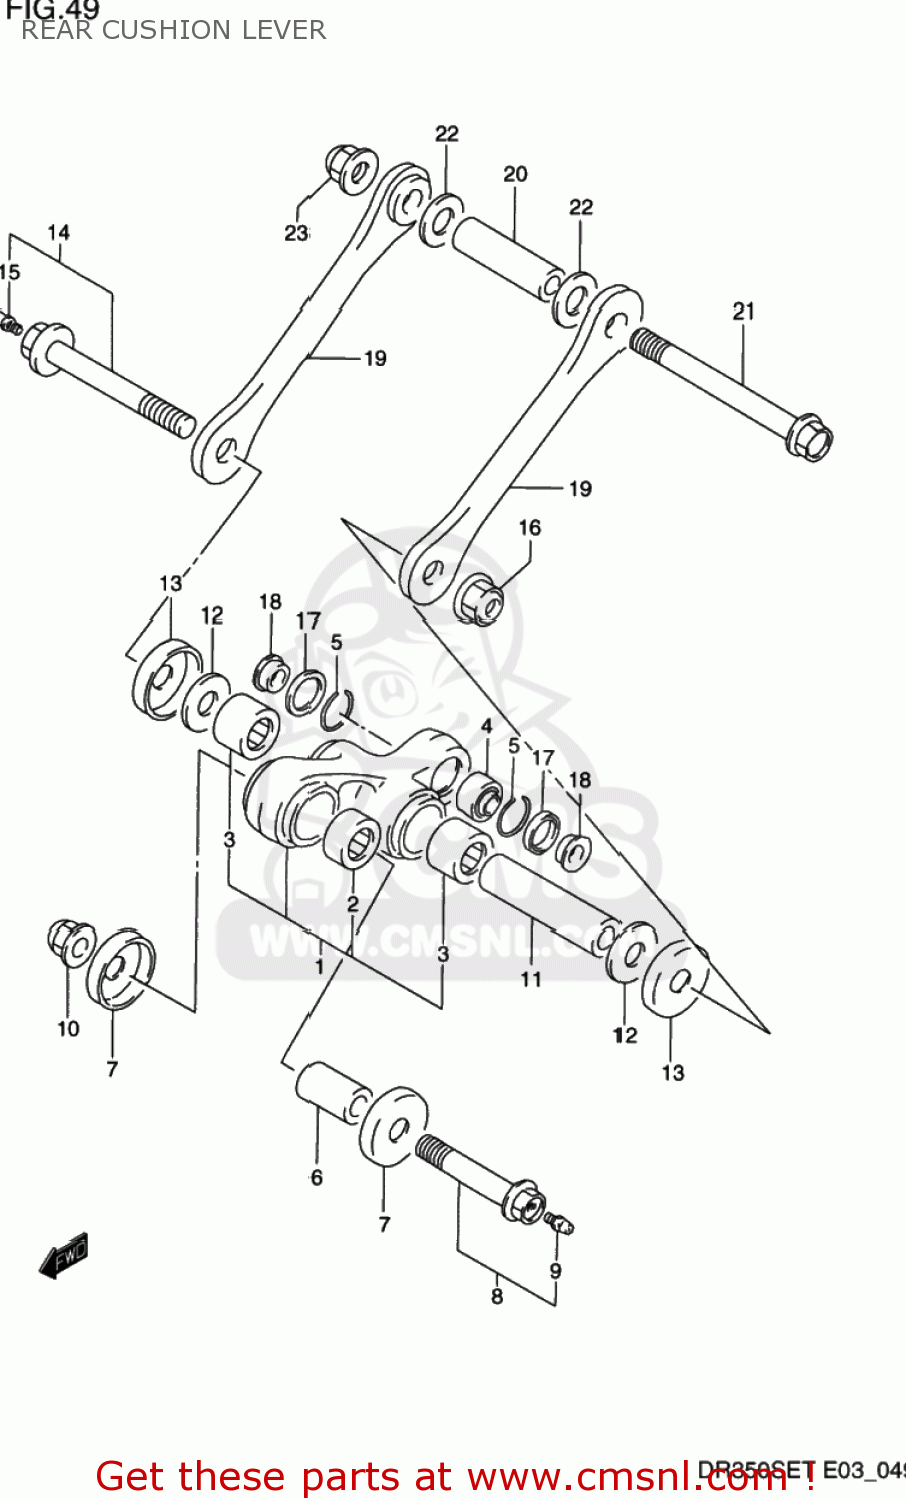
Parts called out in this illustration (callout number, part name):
1	LEVER SET,RR CUSHION
2	BEARING(20X27X32)
3	BEARING(20X27X23.5)
4	BEARING,RR CUSHION LEVER
5	RING,STOPPER
6	SPACER,RR CUSHION LEVER FR
7	SEAL,REAR CUSHION LEVER
8	BOLT,RR CUSHION LEVER FR
9	GREASE NIPPLE
10	NUT 12MM
11	SPACER,RR CUSHION LEVER CTR
12	WASHER
13	SEAL,RR CUSHION LEVER
14	BOLT,RR CUSHION LEVER CTR
15	GREASE NIPPLE
16	NUT
17	SEAL,OIL(17X24X3)
18	COLLAR
19	ROD,RR CUSHION
20	SPACER,RR CUSHION ROD
21	BOLT,RR CUSHION ROD
22	WASHER
23	NUT
